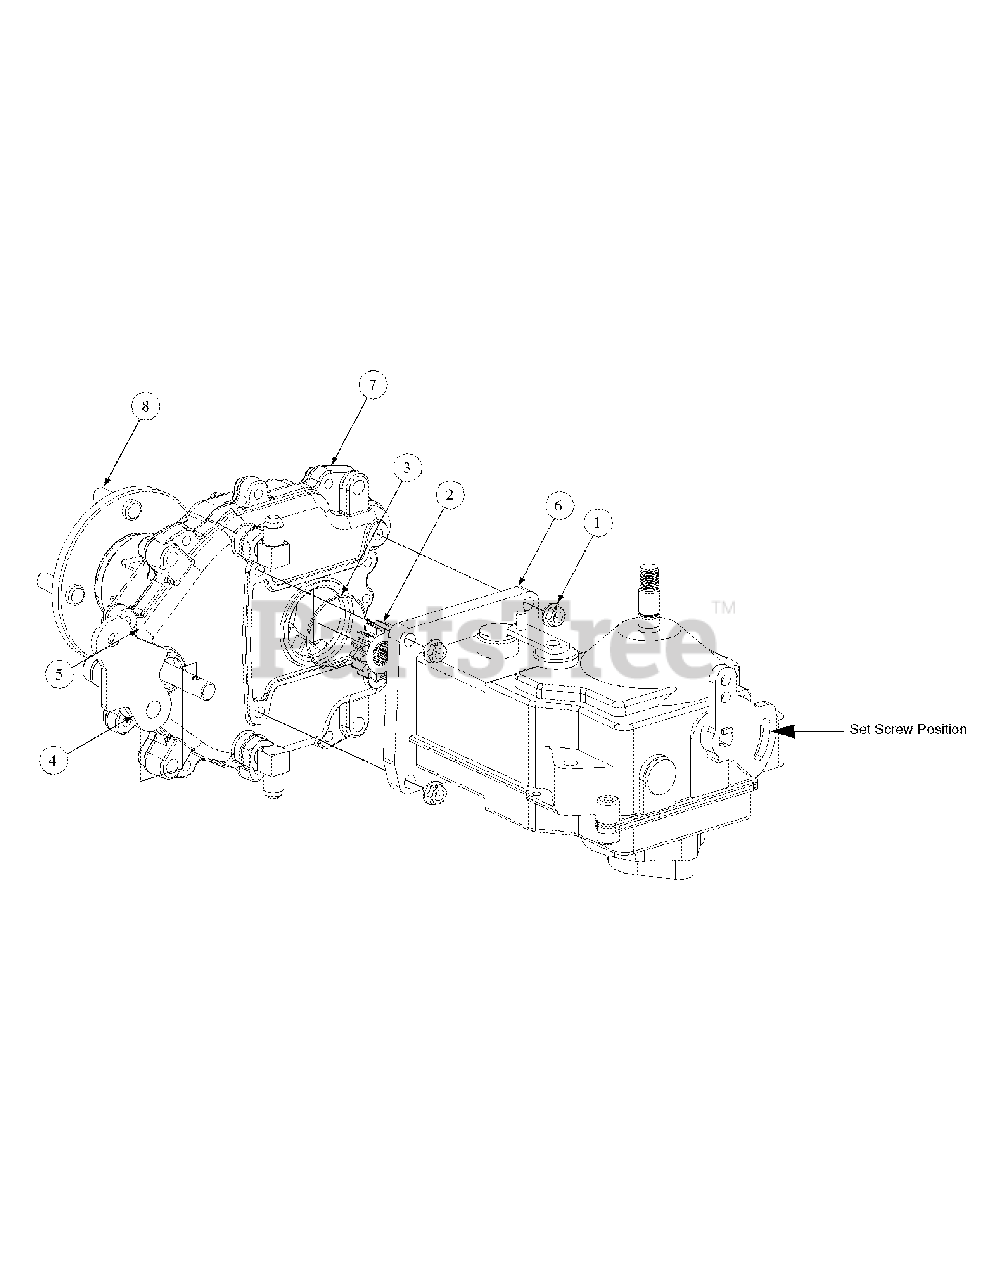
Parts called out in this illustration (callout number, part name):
1	Lock Nut, Hex Flange 5/16-18
2	Gear, Spur, 14T
3	O-Ring, 2.00 x .070
4	Parking Brake Lever
5	Pin, Spirol, 3/16 x 1.25 HD
7	Transmission Assembly
8	Rib Neck Stud, 1/2-20
9	Set Screw, 5/16 - 24 x 1.25
